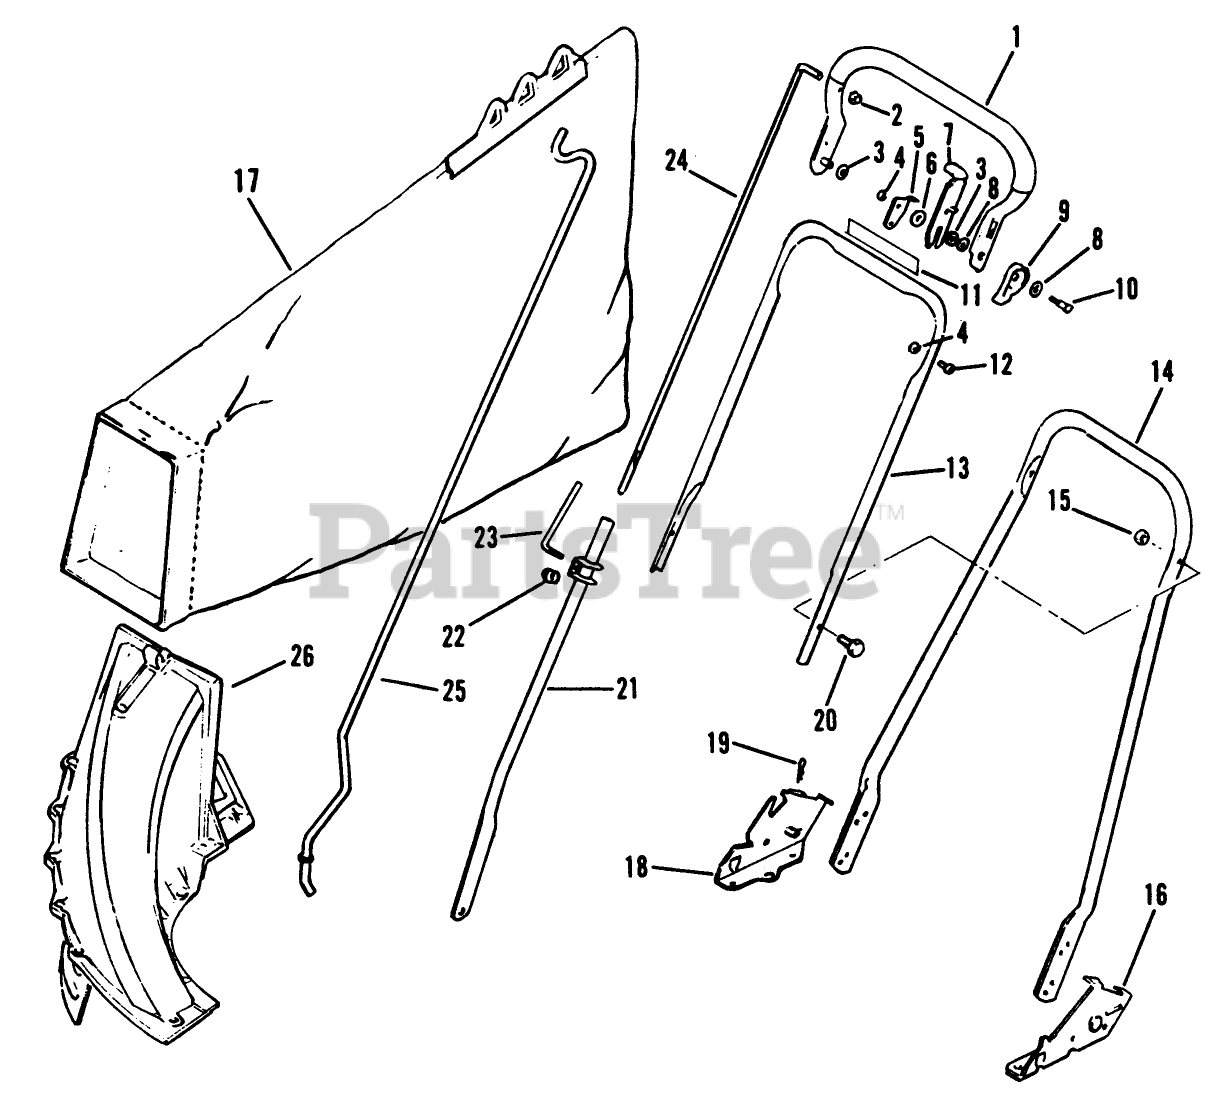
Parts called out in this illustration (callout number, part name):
1	Handle Grip Assy.
3	WASHER M
4	LOCKNUT E
5	HANDLE STOP
6	WASHER
7	LEVER LOCKOUT
10	BOLT PIONEER
11	Decal
12	SCREW-HANDLE STOP
14	HANDLE SECTION *B
15	LOCKNUT E
16	BRACKET ASM - HANDLE, SP, LH
18	BRACKET ASM - HANDLE, SP, RH
19	HAIR PIN
24	ROD CONTROL
25	ROD GRASSBAG
